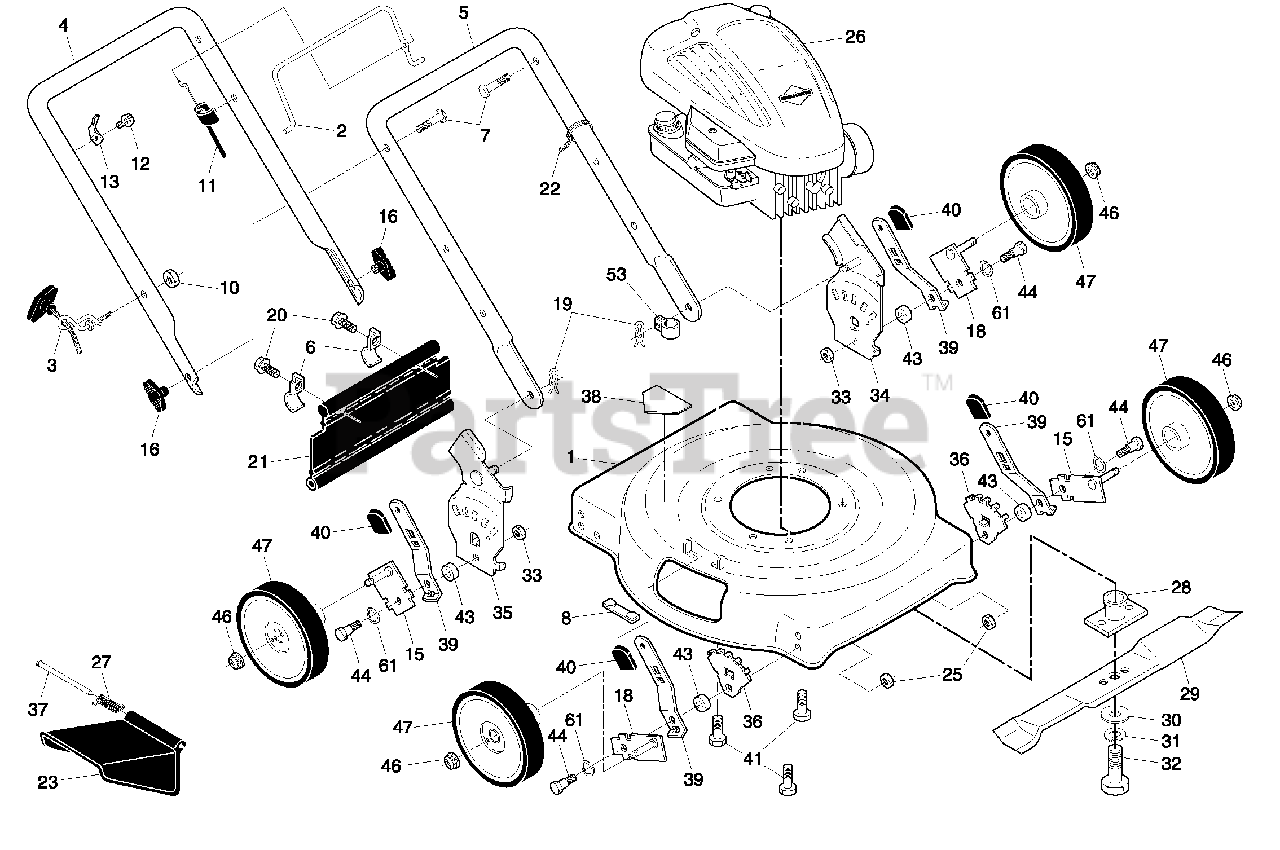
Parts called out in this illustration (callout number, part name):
1	Kit, Housing
2	Control Bar
3	Rope Guide
4	Upper Handle
5	Lower Handle
6	Shoulder Bolt 5/16-18 x 1/2
7	Handle Bolt 5/16-18
8	Clip, Closeout
10	Locknut, Hex 1/4-20
11	Engine Zone Control Cable
12	Screw, Hex Head, Threaded, Rolled #10-24 x 1/2
13	Up-Stop Bracket
15	Axle Arm Assembly, Left Front & Right Rear
16	Handle Knob
18	Axle Arm Assembly, Right Front & Left Rear
19	Hairpin Cotter
20	Screw, Tapping, Hex Washer Head #10-24
21	Rear Deflector
22	Wire Tie
23	Discharge Guard
25	Nut, Hex, Flangelock 5/16-18
27	Torsion Spring
28	Blade Adapter
29	22" Blade
30	Hardened Washer
31	Helical Lockwasher 3/8
32	Screw, Hex Head, Grade 8, 3/8-24 x 1-3/8
33	Nut, Hex, Flangelock 5/16-18
34	Wheel Bracket Support (Left)
35	Wheel Bracket Support (Right)
36	Wheel Bracket Adjuster
37	Hinge Rod
38	Danger Decal
39	Selector Spring
40	Selector Knob
41	Screw, Hex Head, Threaded, Rolled 3/8-16 x 1
43	Spacer
44	Shoulder Bolt 5/16-18 x .33
45	Wheel & Tire Assembly, Rear
46	Nut, Hex, Flangelock 3/8-16
47	Wheel & Tire Assembly, Front
53	Clip, Cable
61	Washer, Curved, Cylindrical
61	Operator's Manual, English
61	Operator's Manual, French
61	Replacement Parts Manual
